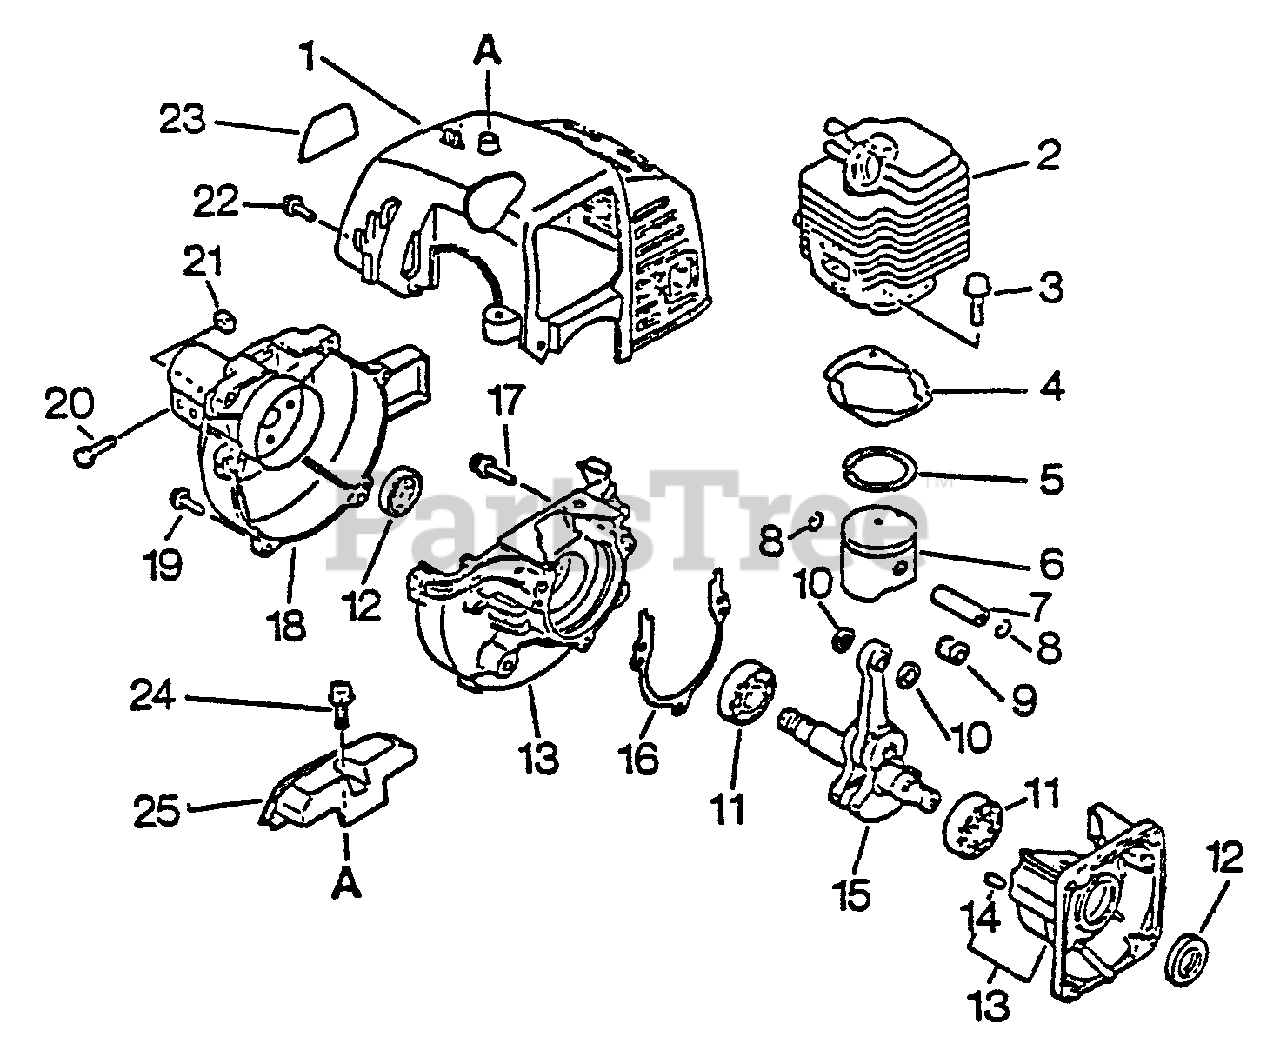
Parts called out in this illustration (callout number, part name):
1	COVER, ENGINE - GRAY
2	CYLINDER
3	SCREW - 5X22
4	GASKET, CYLINDER
5	RING, PISTON
6	PISTON KIT
7	PIN, PISTON
8	RING, RETAINING
9	BEARING, NEEDLE
10	SPACER, PISTON
11	BEARING, BALL - 6201
12	SEAL, OIL
13	CRANKCASE KIT
14	PIN - LOCATING
15	CRANKSHAFT ASSY
16	GASKET, CRANKCASE
17	SCREW - 5X28
18	FAN CASE ASSY
19	SCREW - 4X18
20	BOLT - 5X28
21	NUT - 5 -- SQUARE
22	SCREW - 4X12
23	LABEL - MODEL
24	SCREW - 5X16 -- TAPPING
25	GUARD, TOP - BLACK
